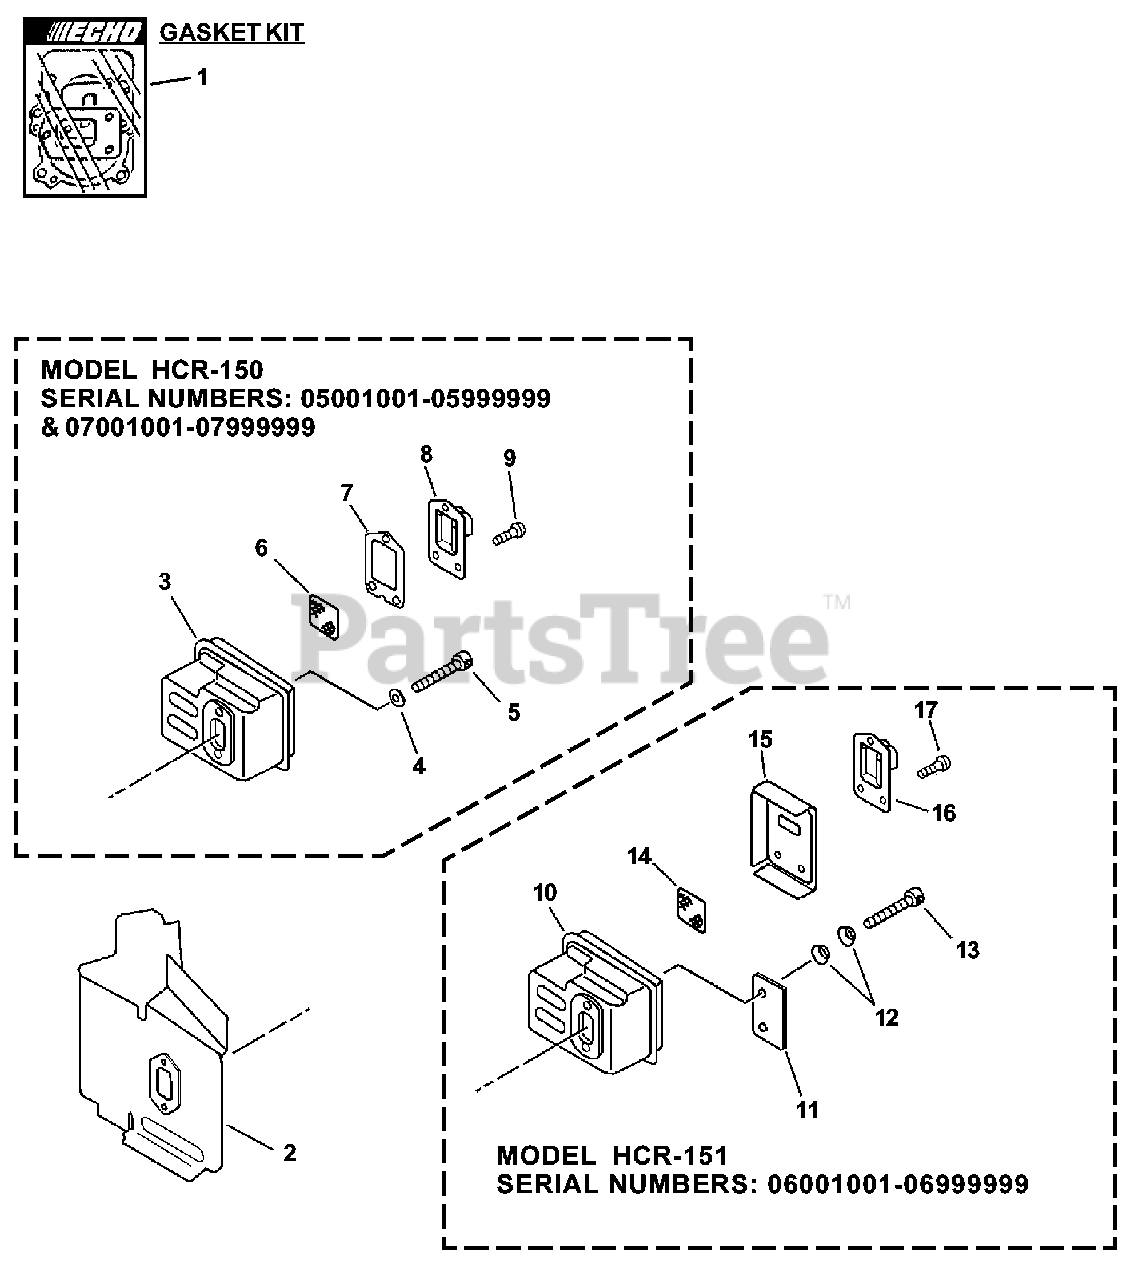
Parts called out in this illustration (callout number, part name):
1	GASKET KIT
2	HEAT SHIELD, EXHAUST
4	WASHER, FLAT 5.5×10×0.8
5	BOLT M5×50
6	SCREEN, SPARK ARRESTER
7	GASKET, EXHAUST
8	GUIDE, EXHAUST
9	SCREW 4×10
10	MUFFLER
11	PLATE, EYE
12	CONICAL WASHER
13	BOLT 5×55
14	SCREEN, SPARK ARRESTER
15	GASKET, EXHAUST
16	GUIDE, EXHAUST
17	SCREW 4×12
